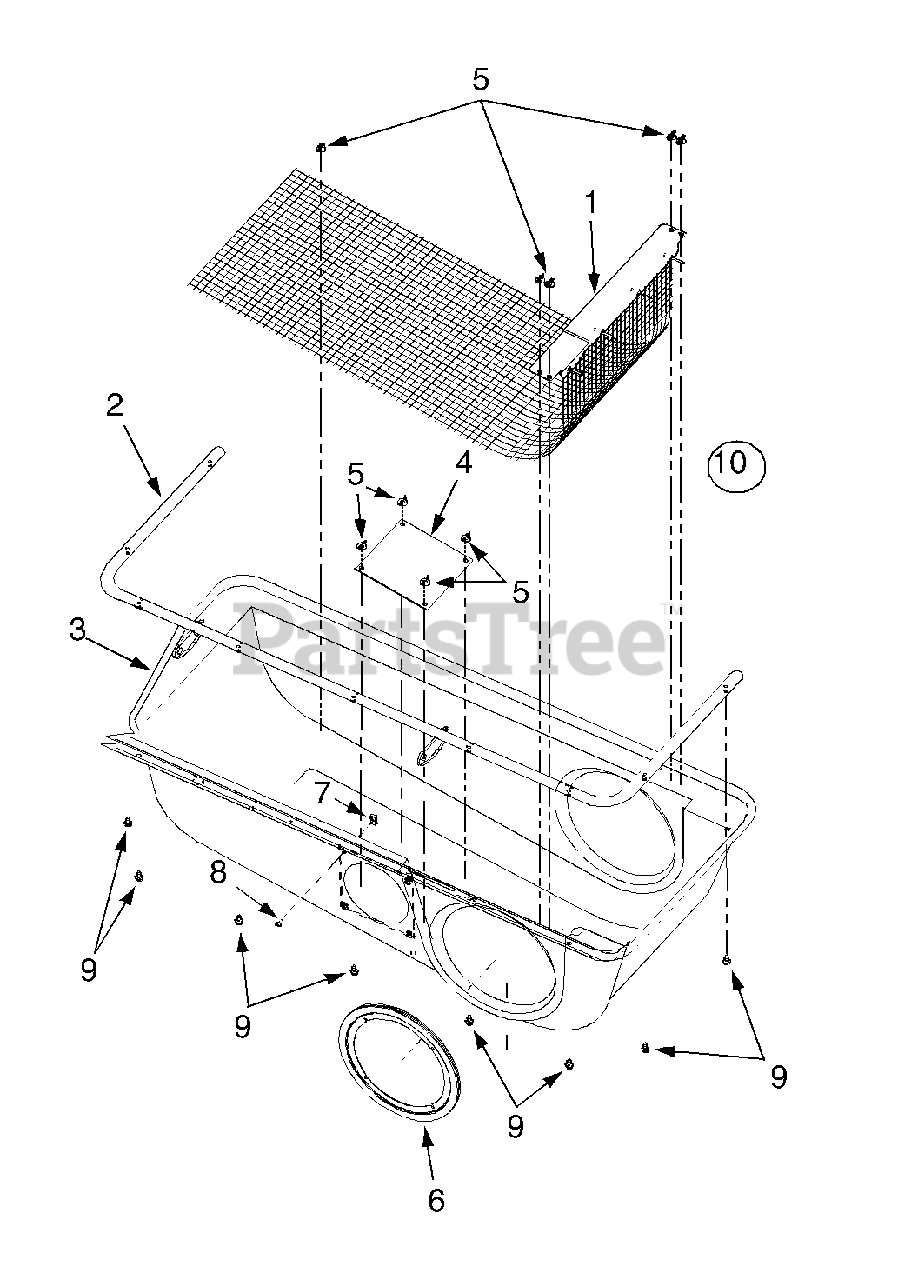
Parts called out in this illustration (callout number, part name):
3	Grass Catcher Cover
4	Plastic Plate
5	Zip Twist Fastener
6	Tube Seal
7	U-Type Speed Nut
8	Screw, #10-16 x 0.5"
9	Hex Screw, 1/4-20 x 0.5"
10	Grass Catcher Cover Assembly
